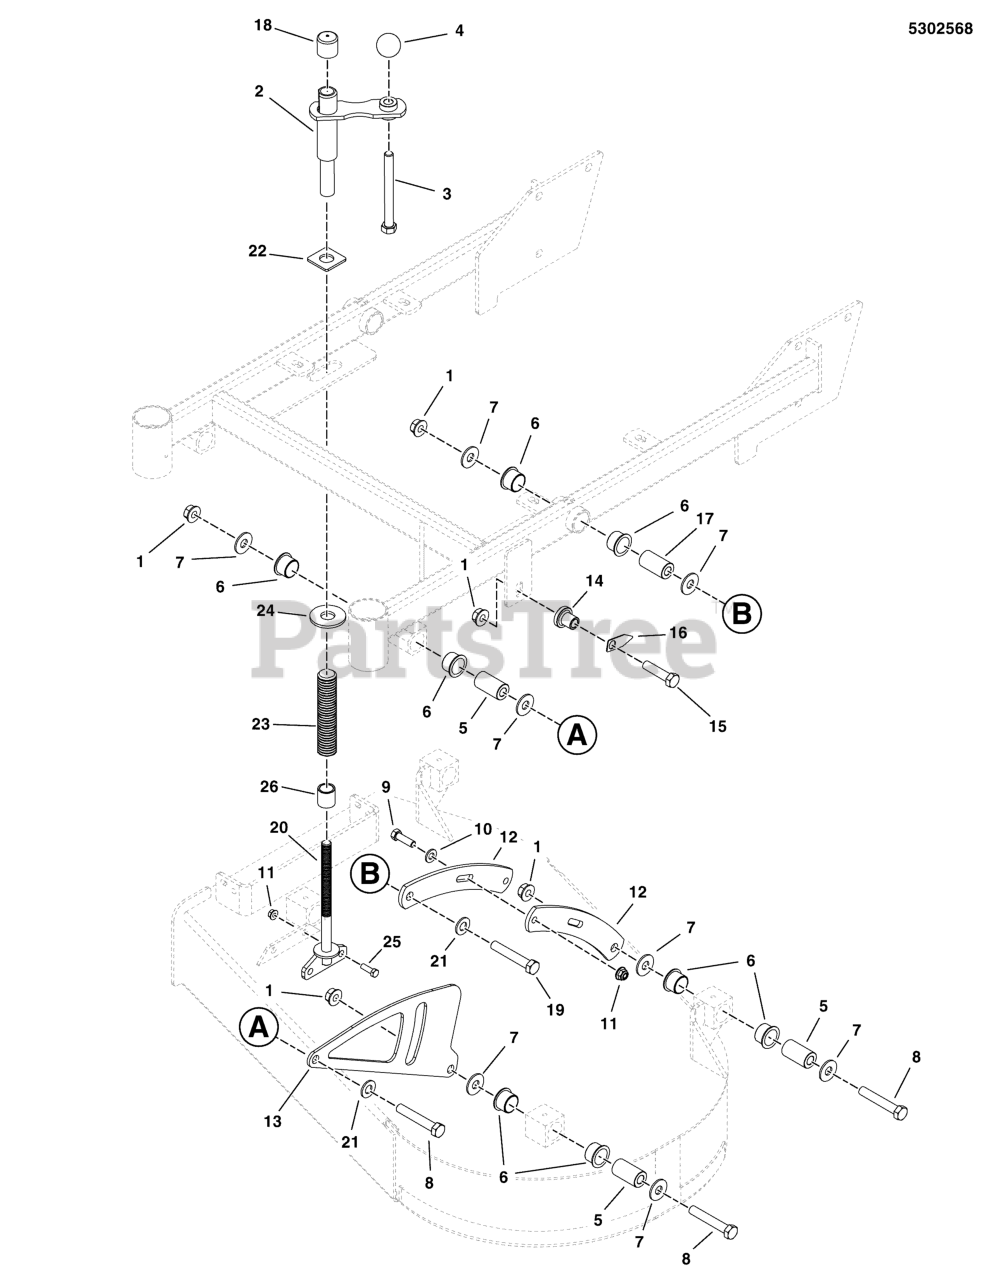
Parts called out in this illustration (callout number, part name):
1	NUT, Hex Flange, Nylock, 1/2-13
2	DECK CRANK, SW30 - BLK
3	BOLT-1/2-13 X 5-1/2 GD5 YZ
4	KNOB, PLASTIC, 1/2-13
5	SPACER, .52 X 1.00 X 1.83, CZ
6	BUSHING, 1.00X1.13X.75, PLA
7	WASHER, 1/2 USS
8	BOLT, 1/2-13 X 3" GD5 CZ
9	BOLT, 3/8-16 X 1-1/4" GD5 CZ
10	WASHER, 3/8 GD.9 FLAT
11	NUT, 3/8-16 HEX NYLOCK FLANGE
12	BAR, DECK LIFT, ADJUSTER, SW30 - RED
13	PLATE, DECK HEIGHT INDICATOR - SNP RED
14	SPACER, .52 X .75 X 1.06 SHLDR, CZ
15	BOLT, 1/2-13 X 2" GD5 CZ
16	POINTER, DECK HEIGHT, SW30
17	SPACER, .50 X 1.00 X 2.25
18	CAP, VINYL, 1.062 X 1.00 BLK
19	BOLT, 1/2-13 X 3-1/2, HEX HD, GD5, CZ (SV)
20	ROD, DECK LIFT, SW30-52-61
21	WASHER, 1/2 SAE
22	WASHER, SQ, .823ID, X 1.63SQ X .14TH, CZ
23	SPRING, COMP, .840 X 1.044 X 6.7, BLK
24	WASHER, 3/4 USS
25	BOLT, 3/8-16 X 1" GD5 CZ
26	SPACER, .64 X .82 X .88, CZ
